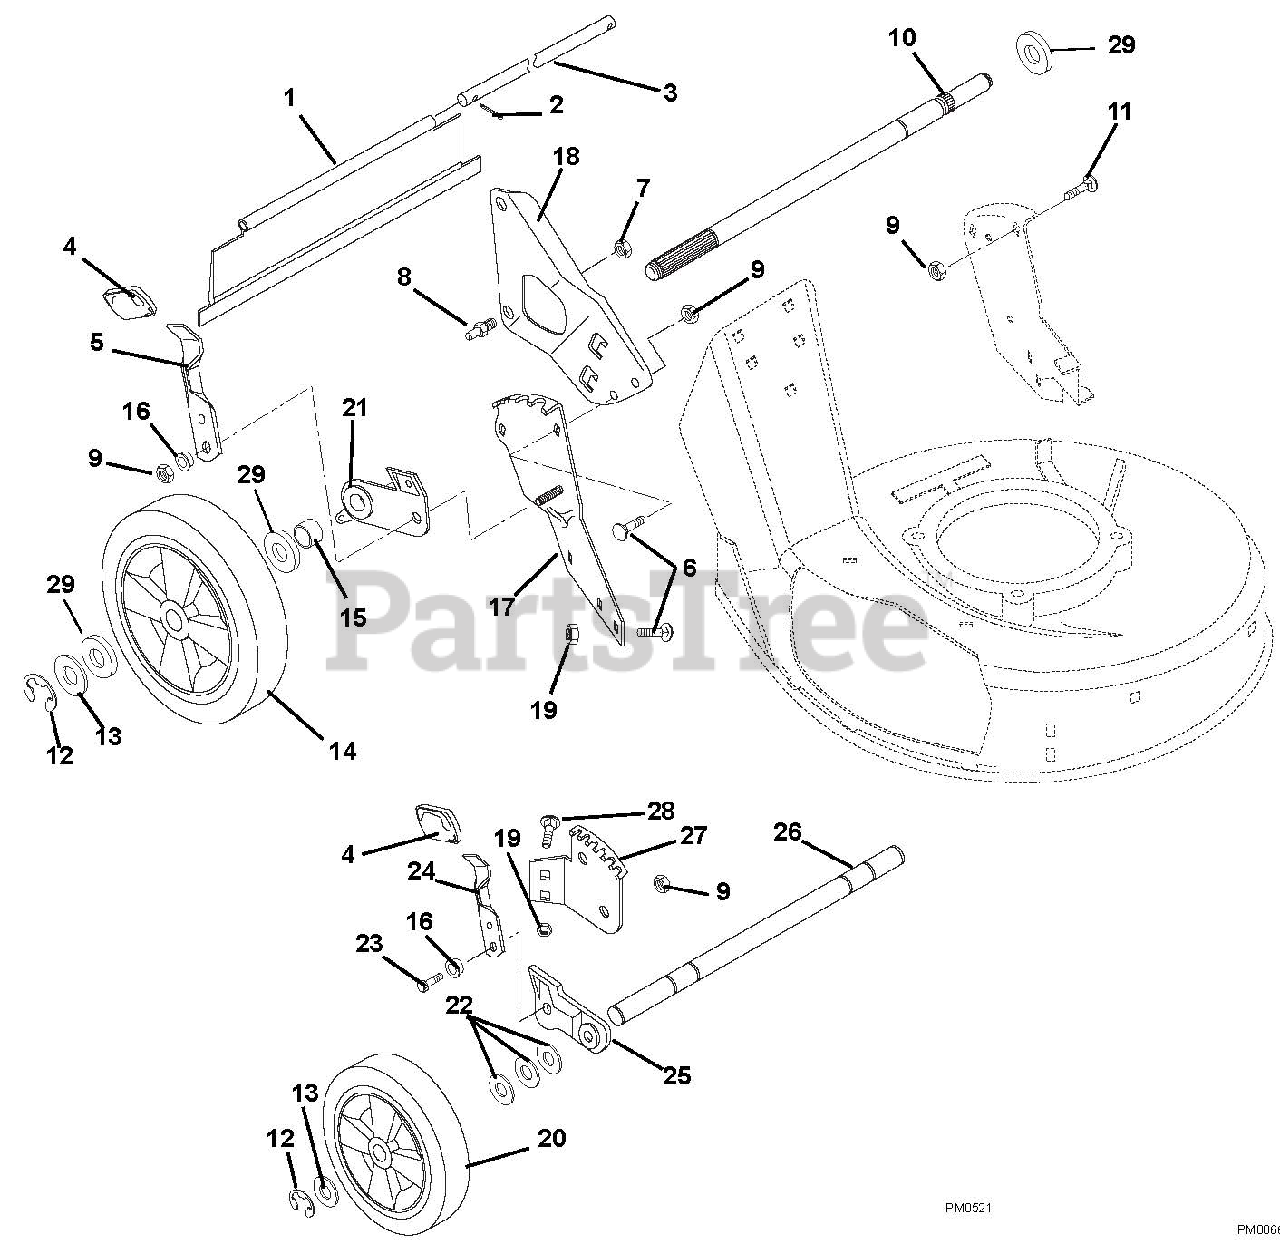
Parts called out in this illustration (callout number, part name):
1	REAR PROTECTIVE GUARD, S.P.
2	@PIN-CTR .06X.50 EXTPRSQCT YWZ
3	ROD
5	LEVER, HEIGHT ADJUSTMENT
6	@BLT-RHDSSQNK .31-18X.62 G5YZ
7	@NUT-LK-CTR .38-16 YWZC
8	HANDLEBAR STUD
9	@NUT-LK-TOP-FLG .31-18 YWZC
10	REAR AXLE,5/8 DIA
10	REAR AXLE-PUSH MOWER MM
11	BLT-RDHDSQNK .31-18X1.0 SHTYZ
12	RG-RTNG-EXT .500X.042 (E)
13	WSHR-FL-STL .505X.880X.072 YWZ
14	WHL, LH 10.50"
14	WHL, RH 10.50"
14	10 1/2 TIRE SKIN
14	TIRE, REAR 10X1.75 #6 GRAY
15	SPACER TUBE, SELF PROPEL
15	SPACER TUBE PUSH RH
16	BSHG-FLG .32X.500X.344X.880
17	QUADRANT, REAR LH
17	QUADRANT, REAR RH
18	RH HANDLEBAR MTG. BRKT
18	LH HANDLEBAR MTG. BRKT
19	@NUT-LK-TOP-FLG .31-18 YWZC
20	WHL 7.50" .50 BORE, 1.50 HUB
21	REAR ADJUSTMENT BRACKET L.H.
21	REAR BRACKET & BEARING ASSY RH
22	WSHR-FL-STL .52X.827X.062 YWZC
23	@BLT-HEX .31-18X1.00 GR5 YWZC
24	FRONT HEIGHT ADJUSTMENT LEVER
25	LEFT ADJUSTOR BRACKET ASSEMBLY
25	RIGHT ADJUSTOR BRACKET ASSEMBL
26	FRONT AXLE
27	FRONT QUADRANT, LH
27	FRONT QUADRANT, RH
28	@BLT-RDHDSQNK .31-18X.50 G5YZ
29	SPACER .531 X 1.00 X .225
